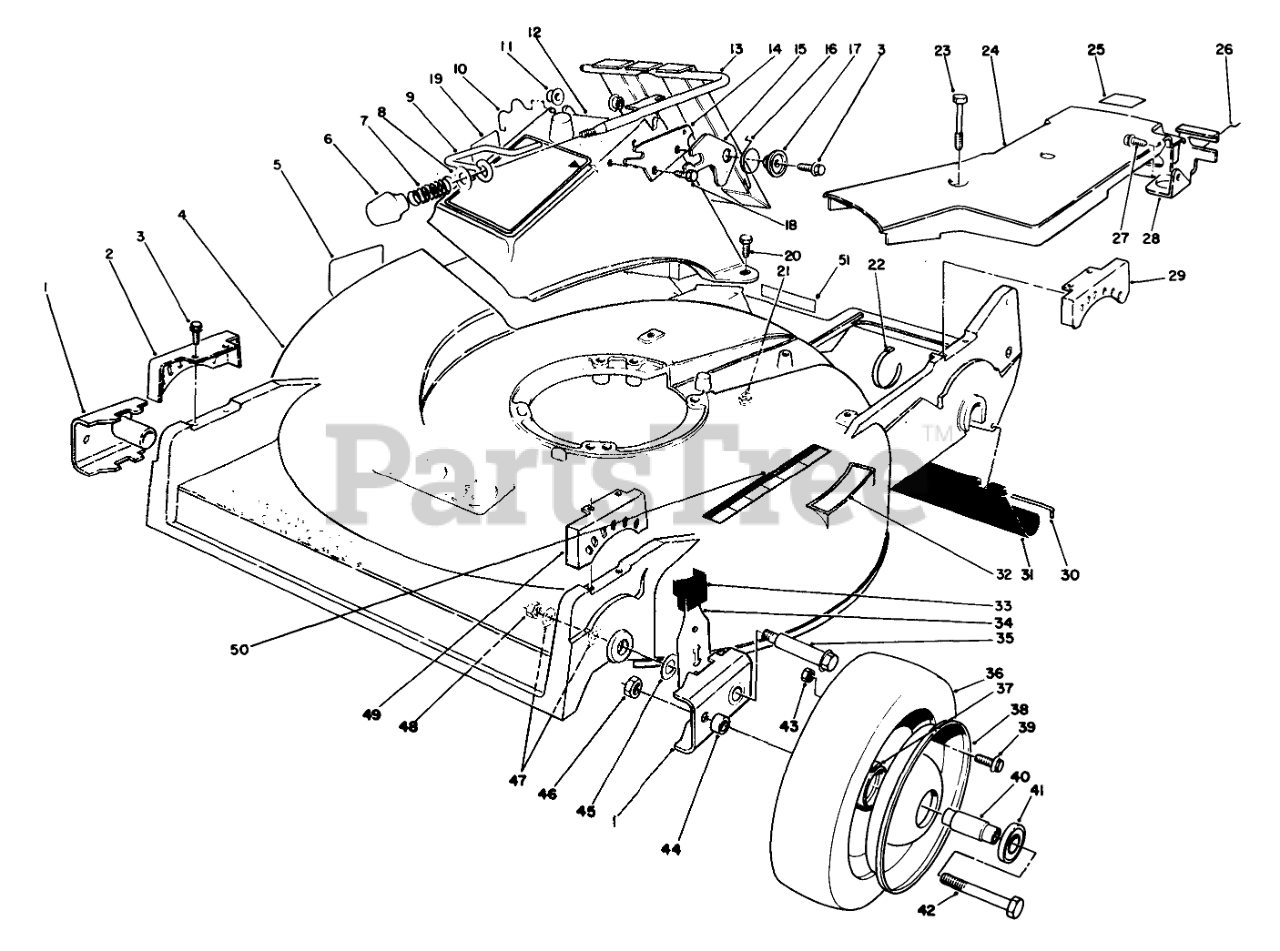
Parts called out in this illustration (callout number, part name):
1	ARM-PIVOT, FRONT
2	QUADRANT-FRONT, RH
3	SCREW-HWHTF
4	Housing-Commercial (Incl. Ref. #5 & 32)
5	Decal Danger
7	COMPRESSION SPRING
8	WASHER-FLAT
9	DOOR LATCH
10	DOOR RETAINER
11	BUSHING-NYLON
12	DISCHARGE CHUTE B
13	DOOR & HANDLE WA
14	DOOR LATCH PLATE
15	SAFETY LATCH
16	TORSION SPRING
17	DOOR SPACER
18	SCREW-HWH
19	Decal-Danger
20	SCREW-HH
21	NUT-LOCK, NI
22	TIE-CABLE
23	SCREW-HHFTF
24	Cover-Belt
25	Label-Grease
26	RETAINER-CABLE
27	SCREW-HWHTF
28	Bracket-Traction Adj.
29	QUADRANT-REAR, LH
30	ROD-SHIELD
31	SHIELD-TRAILING
32	DECAL - STEP PAD INT'L
33	KNOB-ARM
34	FRONT SPRING ARM ASM
35	WHEEL BOLT
37	HUB-BEARING
38	Wheel-Half
39	SCREW-HHF
40	SPACER-BEARING
41	BEARING-WHEEL
42	SCREW-HH
43	NUT-LOCK, NI
44	SPACER-WHEEL
45	WASHER-THRUST
46	NUT-LOCK, CONE
47	WASHER
48	Nut
49	QUADRANT-FRONT, LH
50	DECAL - DANGER
51	Decal
